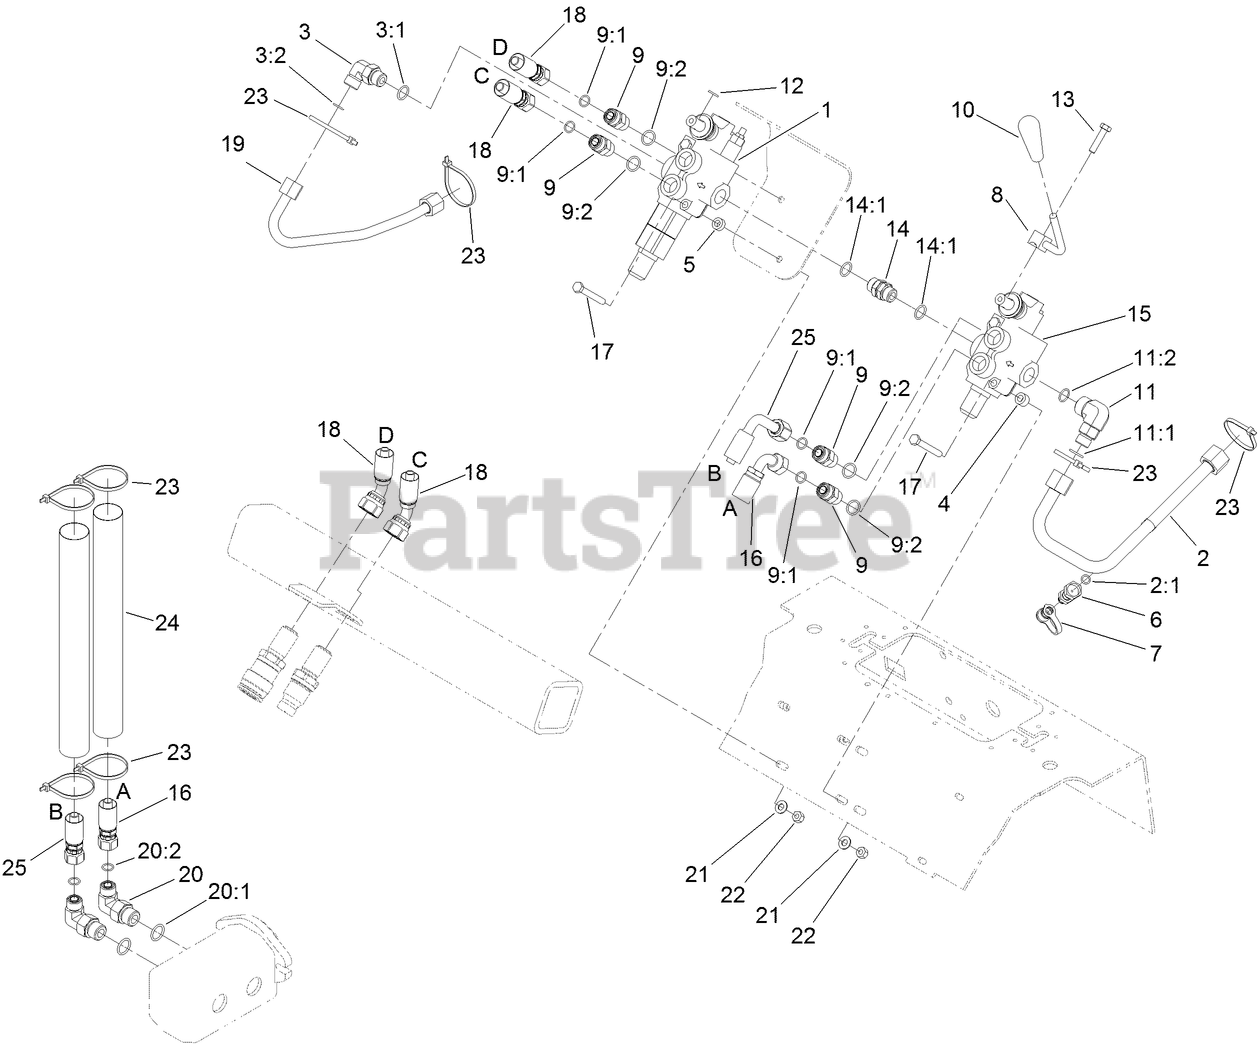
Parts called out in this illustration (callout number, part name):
1	VALVE-HYD, AUXILIARY
2	HYD TUBE ASM
2:1	O-RING
3	FITTING-ELBOW-90 DEG
3:1	O-RING
3:2	O-RING
4	SPACER
5	SPACER
6	NIPPLE-TEST
7	CAP-DUST
8	LEVER-CONTROL
9	FITTING-STRAIGHT
9:1	O-RING
9:2	O-RING
10	KNOB-TAPERED
11	Fitting-Elbow, 90 DEG
11:1	O-RING
11:2	O-RING
12	WASHER-LOCK
13	SCREW-HH
14	FITTING-THREAD, STRAIGHT
14:1	O-RING
15	VALVE-SELECTOR, HYD
16	HOSE-HYD
17	SCREW-HH
18	HOSE-HYD
19	TUBE-HYD
20	FITTING-ELBOW 90
20:1	O-RING
20:2	O-RING
21	WASHER-PLAIN
22	NUT-LOCK, NI
23	TIE-CABLE
24	SLEEVE-THERMAL
25	HOSE-HYD
